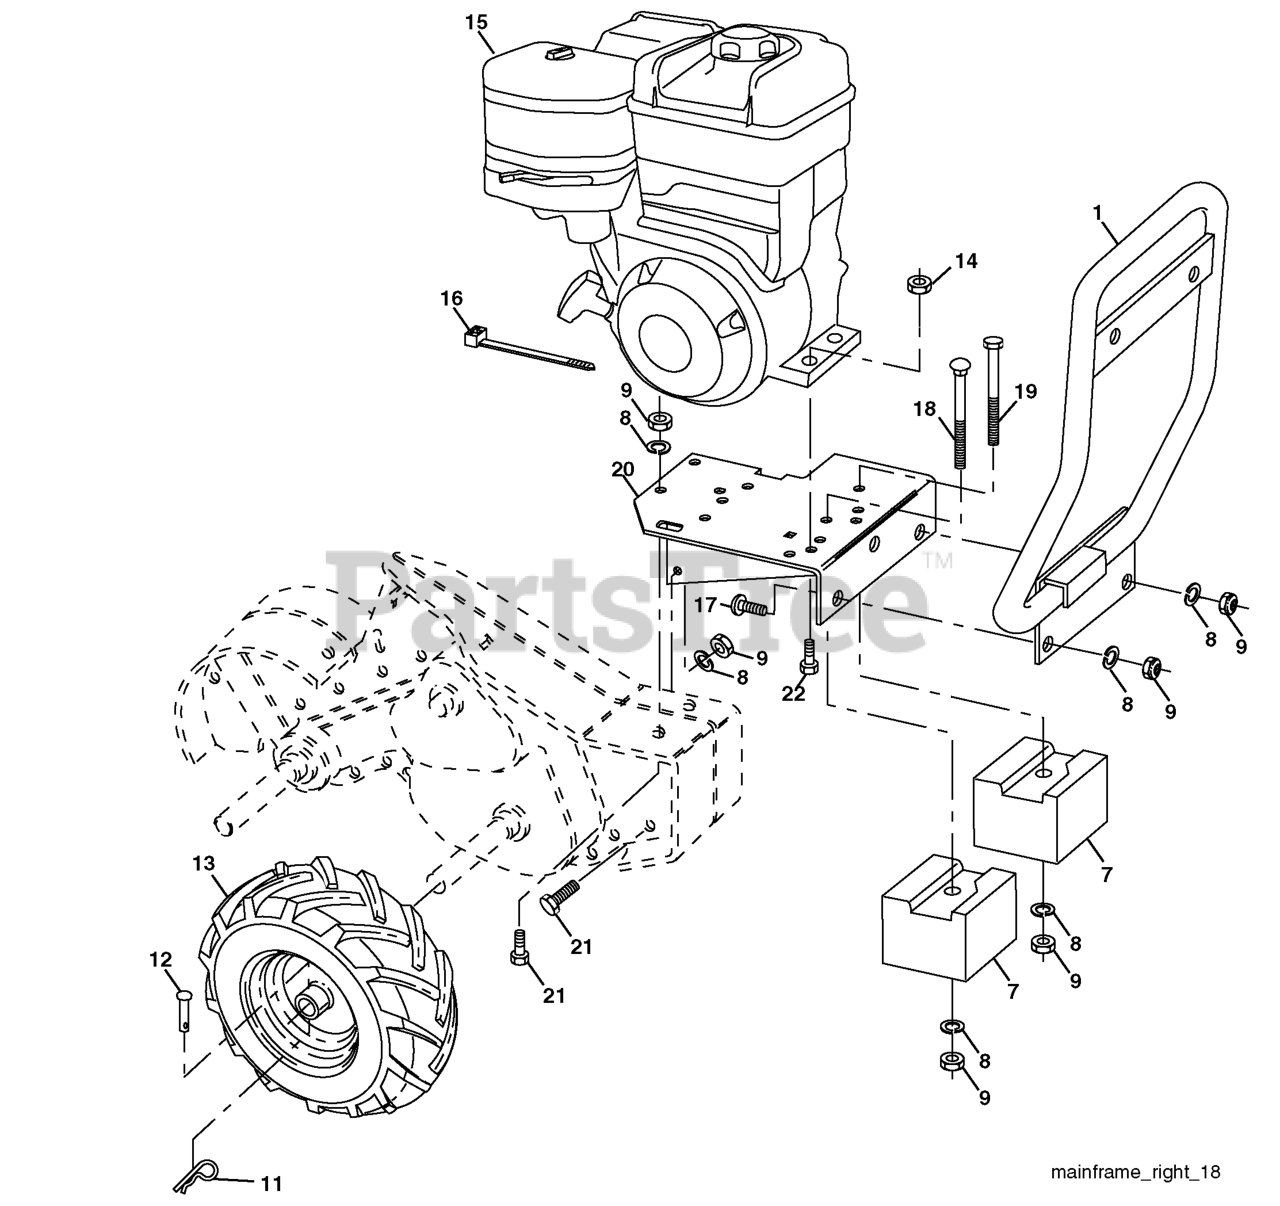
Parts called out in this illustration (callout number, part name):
1	BUMPER.ASM.9HP.TILLER
7	COUNTERWEIGHT
8	WASHER, LOCK 3/8
9	NUT.HEX.3/8-16UNC
11	SPRING TI
13	TIRE.16X4-8.CHEVRON.TILLER
14	LOCKNUT-FLANGE 5/16-18
16	TIE GUIDE
17	BOLT D
18	Bolt 3/8-16 x 4-1/2
19	BOLT, HEX 3/8-16X4-1/2
20	Base Engine
21	BOLT
22	BOLT
